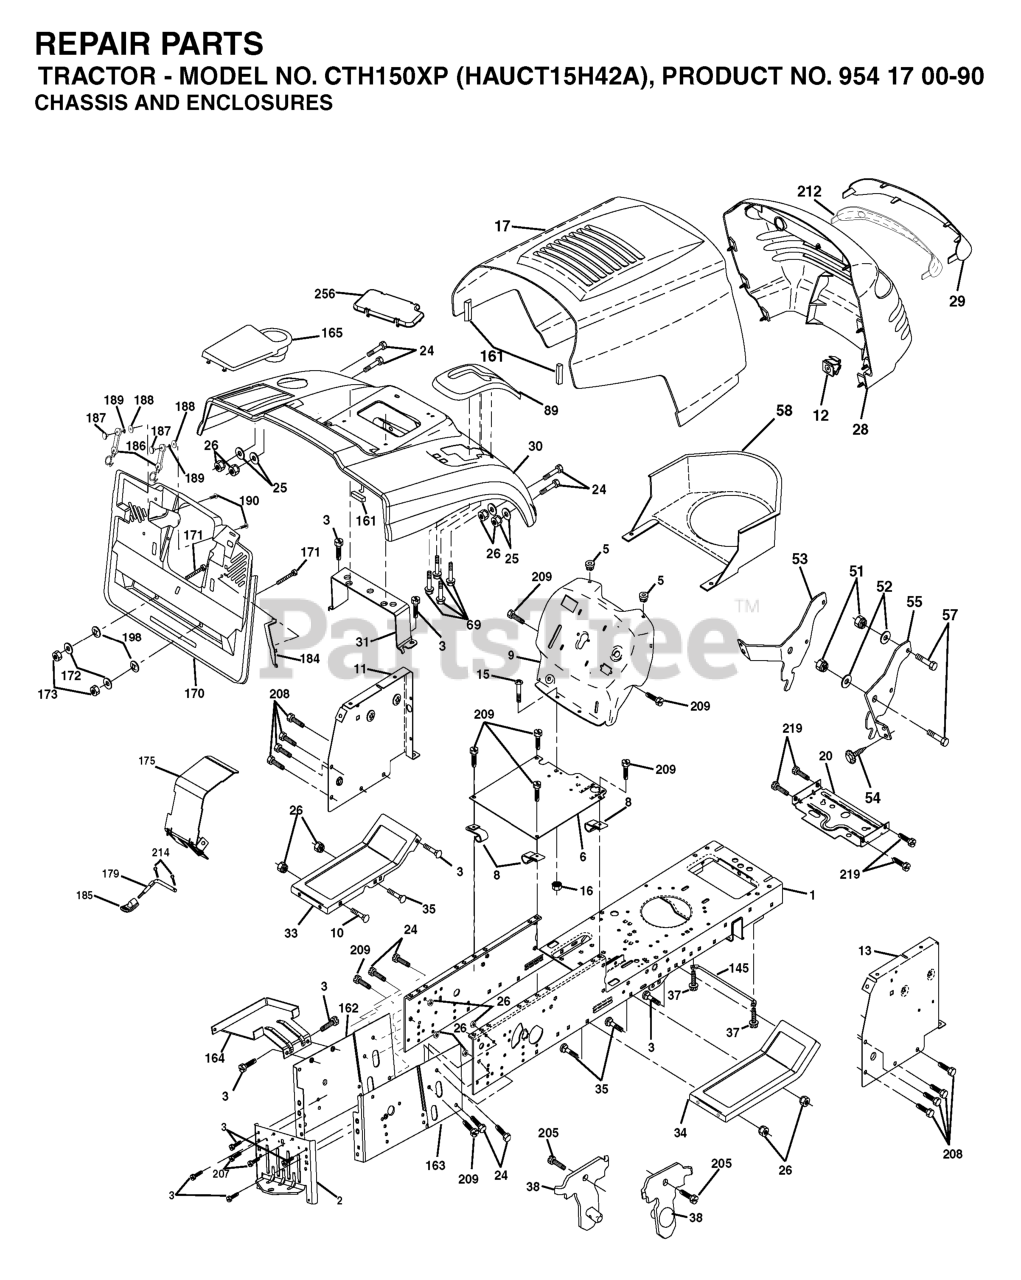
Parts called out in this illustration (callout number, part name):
2	DRAWBAR
3	SCREW 3/8-16X3/4
5	BUMPER.RUBBER.HOOD
6	SADDLE FLAT
8	CLIP,INSULATOR
10	BOLT D
11	PANEL.DASH.LH.LTX
13	PANEL ASM, DASH RH
15	Screw, Machine, Truss Head 5/16-18 UNC x 3/4
16	NUT
17	HOOD ASM.
20	PLATE MTG.BATTERY/FUEL TANK
25	WASHER
26	NUT
28	GRILLE/LENS ASM
29	LENS
31	BRACKET SUPPORT FENDER
33	FOOTREST PNT LH
34	FOOTREST PNT RH
37	Screw 5/16-18 x 1/2 Hex, Self Tapping 5/16-18 x 1/2
38	BRACKET ASM PIVOT MOWER REAR
51	LOCKNUT.NYLOC.1/4-20
53	BRACKET.GRILLE.LH
54	SCREW.HEX.WS.HD.8-18 X 7/8
57	BOLT
58	DUCT, INTAKE AIR
68	NUT
69	SCREW.HI-LO.CONSOLE
71	NUT.CROWNLOCK.1/4
89	COVER.BATTERY.CRD.GREY
145	ROD PIVOT CHASSIS/HOOD
161	EXTRUSION BUMPER (3 2) (2 2)
162	BRACKET
163	BRACKET EXTEN CHASSIS RH CRD
165	RP.COVER.BATTERY.CRD.GREY
172	WASHER
184	BRACKET.ACTUATOR.BAGGER.SRD
186	LATCH ASSY
187	WELDNUT
189	LOCKWASHER #10
190	SCREW
207	SCREW, 5/16-18 X 1/2
208	SCREW 3/8-16X1/2
209	SCREW, 3/8-16X3/4
212	REPL BY 532 1745-03
214	RETAINER M
219	SCREW
256	COVER FENDER CRD
